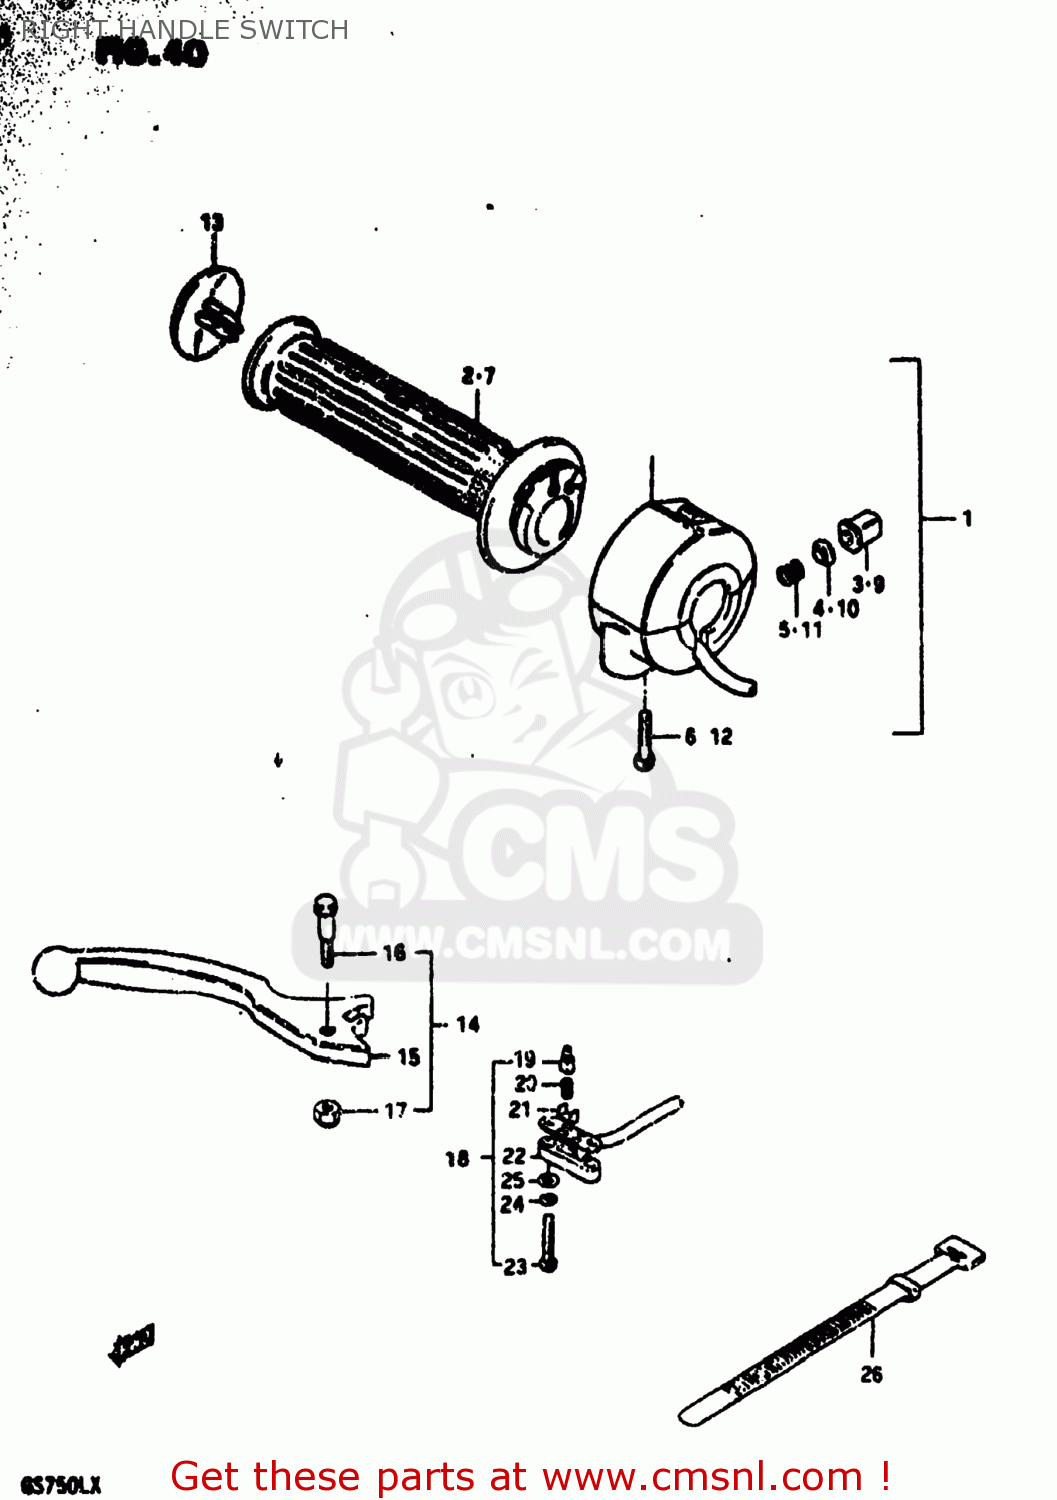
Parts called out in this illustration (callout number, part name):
1	CASE ASSEMBLY,THROTTLE
2	GRIP,THROTTLE
3	BUTTON,HORN
4	CONTACT
5	SPRING
6	SCREW
7	GRIP,THROTTLE
8	CASE ASSEMBLY,THROTTLE
9	BUTTON,HORN
10	CONTACT
11	SPRING
12	SCREW
13	CAP,GRIP END
14	LEVER ASSEMBLY,BRAKE
15	LEVER,BRAKE
16	BOLT
17	NUT
18	SWITCH ASSEMBLY
19	HOLDER
20	SPRING
21	PLATE
22	COVER,FR BK TERMINAL BASE
23	SCREW
24	LOCK WASHER
25	WASHER
26	CLAMP(L:120)
